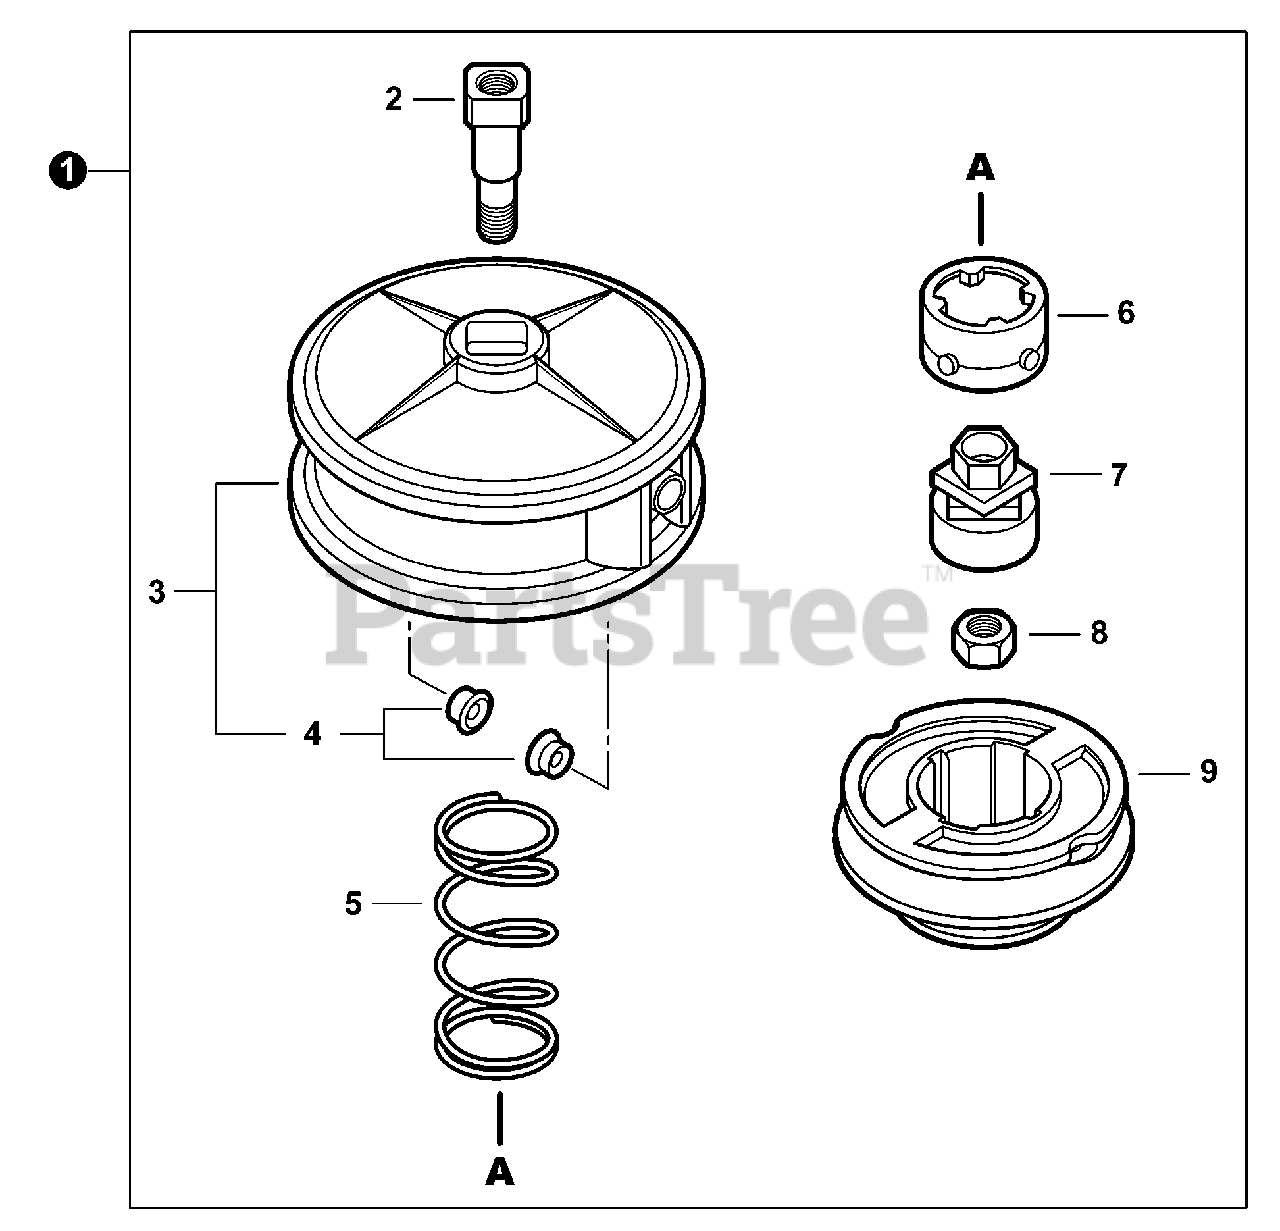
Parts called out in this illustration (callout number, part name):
1	TRIMMER HEAD, U-TURN
2	STUD, ARBOR M10 × 1.25 LH
3	HOUSING ASSY, SPOOL
6	DRIVE, OUTER
7	CAM, INNER
